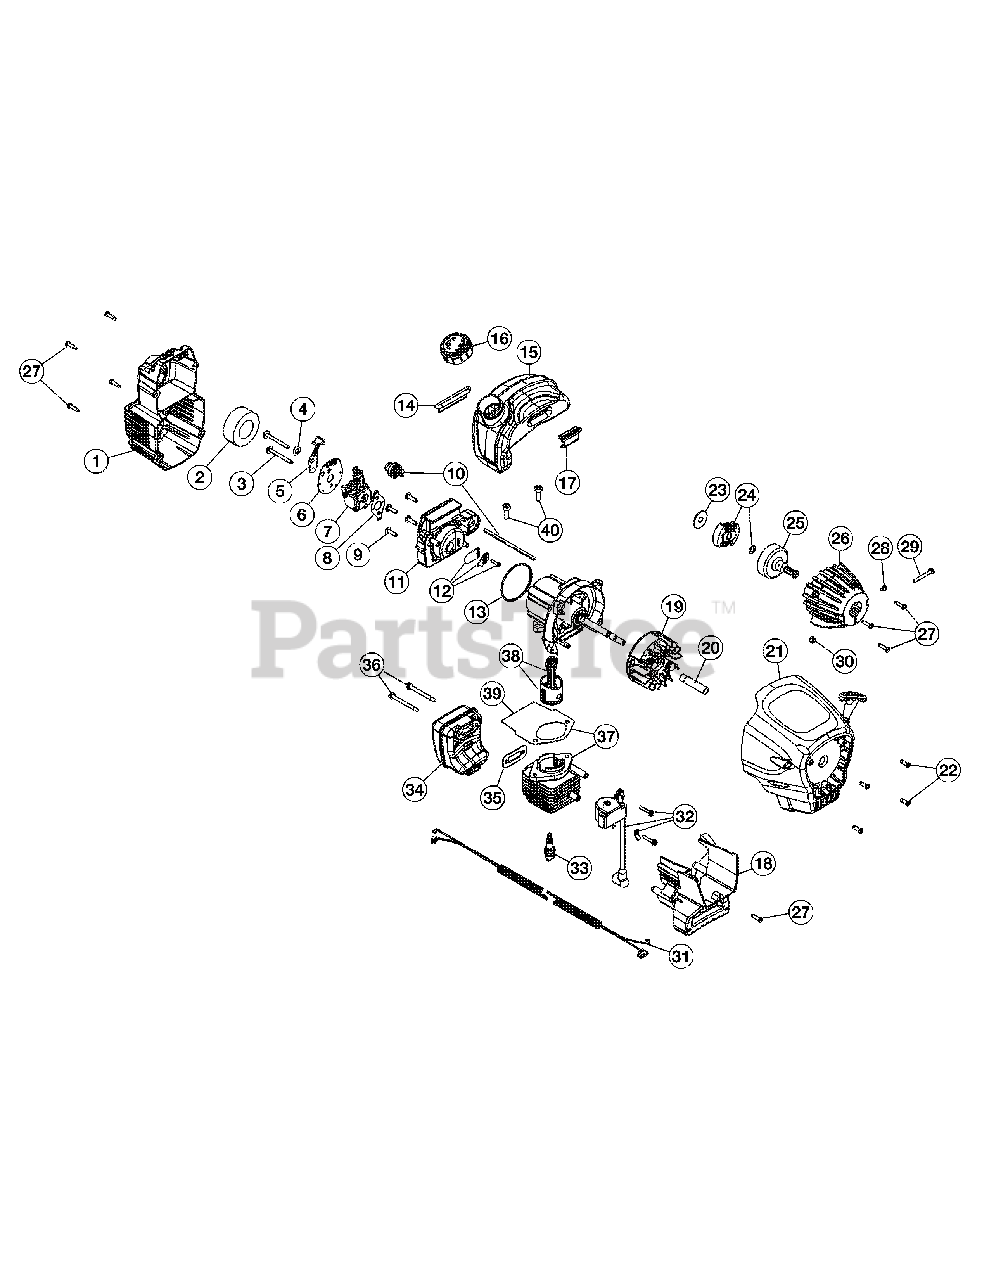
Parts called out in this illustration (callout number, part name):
1	Air Cleaner Cover Assembly (Incl. Ref No. 2 & 27)
2	Air Cleaner Filter
3	Carburetor Mounting Screw Assembly
4	Wavey Washer
5	Choke Lever Assembly
6	Choke Plate Assembly (Incl. Ref No. 5)
7	Carburetor Assembly (Incl. Ref No. 8)
8	Carburetor Gasket
9	Carb Mount Screw
10	Primer & Hose Assembly
11	Carb Mount Assembly (Incl. Ref No. 9, 12 & 13)
12	Reed Assembly
14	Rear Mounting Pad
15	Fuel Tank Assembly (Incl. Ref No. 16)
16	Fuel Cap Assembly
17	Front Mounting Pad
18	Shroud Extension & Stand (Incl. Ref No. 27)
19	Flywheel Assembly
21	Starter Housing Assembly (Incl. Ref No. 22 & 27)
22	Housing Screw
23	Clutch Washer
24	Clutch Rotor Assembly
25	Clutch Drum Assembly
26	Clutch Cover Assembly (Incl. Ref No. 27-30)
27	Cover Screw
28	Anti-Rotation Screw
29	Clamping Screw
30	Clamping Nut
31	Wire Leads and Sleeve
32	Module Assembly
34	Muffler Assembly (Incl. 35, 36 & Spark Arrestor)
35	Exhaust Gasket
36	Muffler Mounting Bolts
37	Cylinder Assembly (Incl. Ref No. 39 & 40)
38	Piston and Rod Assembly
39	Cylinder Gasket
40	Cylinder Bolt
